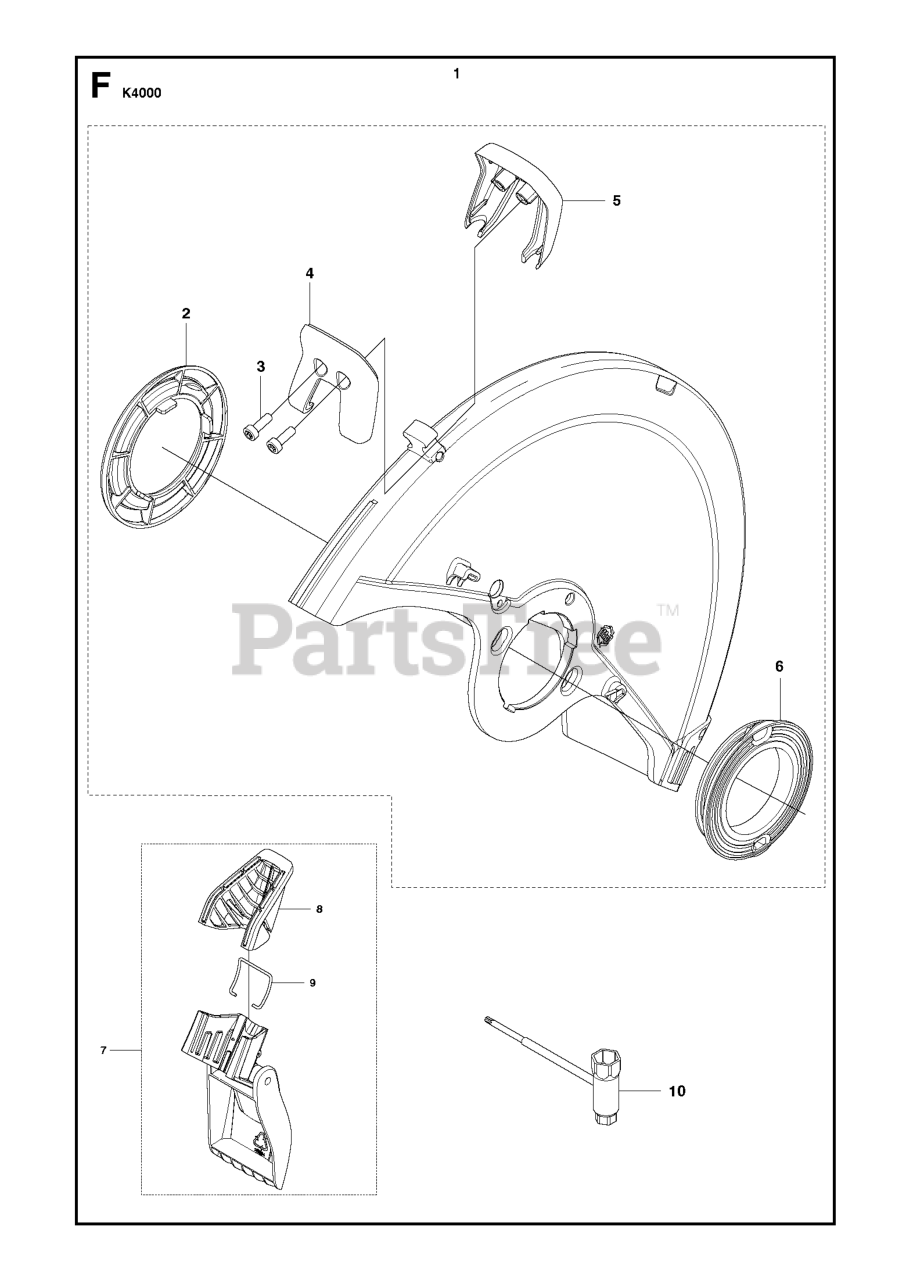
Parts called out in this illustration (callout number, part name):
1	WHEEL GUARD ASSY
2	ADAPTER K3000 MG BLADE GUARD
4	HANDLE HALF K3000 MG LOWER
5	HANDLE HALF K3000 MG UPPER
